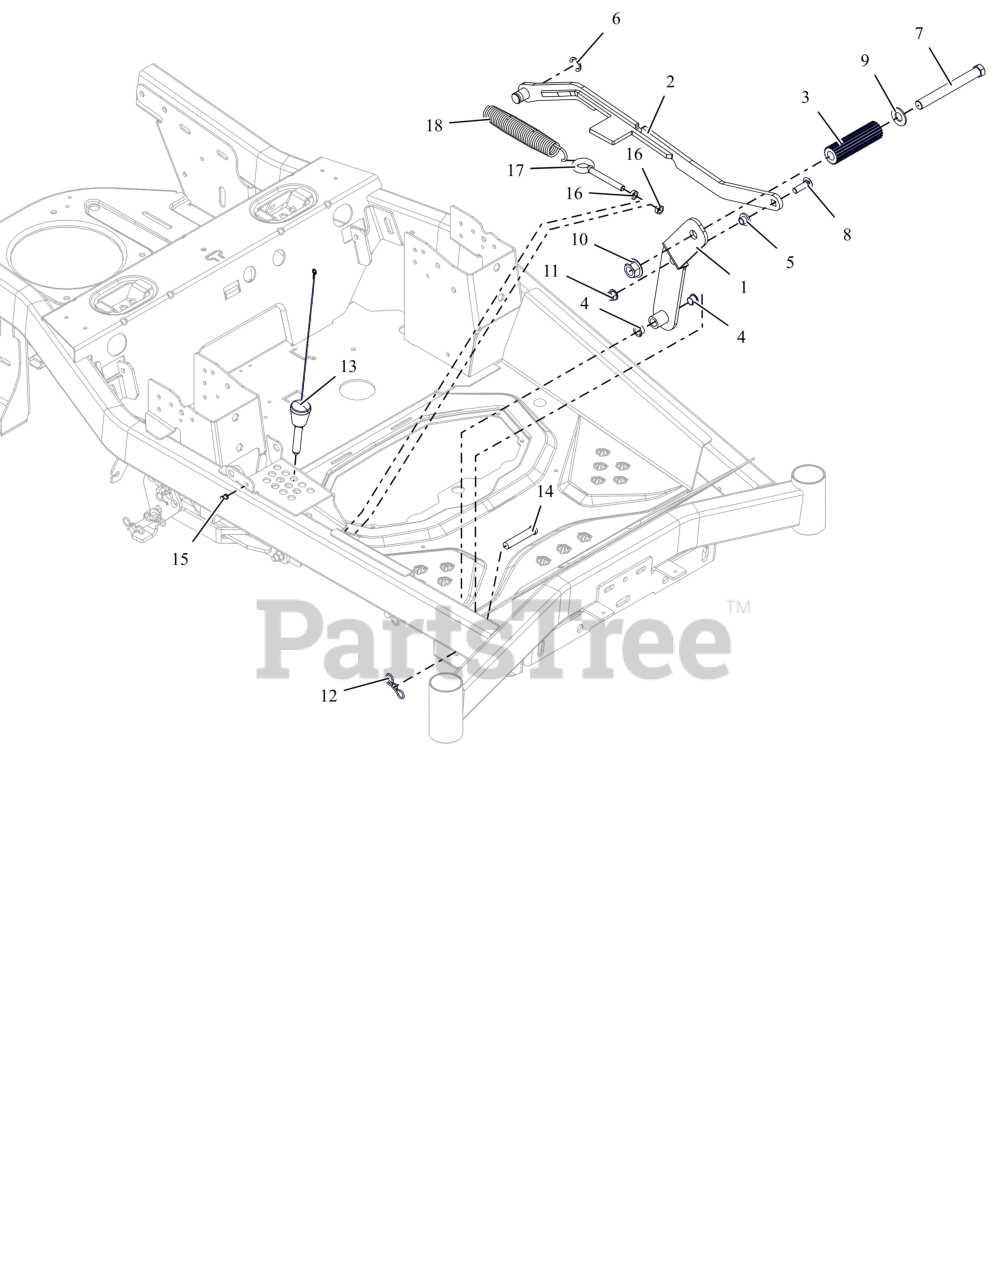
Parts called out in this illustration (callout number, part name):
1	WLDMT- FOOT PEDAL-ORG
2	LINK- DECK LIFT-ORG
3	ROD, FOOT PEDAL (BLACK)
4	BUSHING, POLYLINER-.50 SPLIT
5	BSHG-FLG .385X.500X.875X.406
6	E-RING .750X.050
7	BLT, HEX .62-11X5.50 G5 FBP
8	BLT,RHSSN .38-16X1.25 G5 ZCC
9	WSHRFLT 5/8SAE CARBHARD FBP
10	NUT,FLG-TOP LK .625-11 FBP
11	NUT-LK-CTR-FLG .375-16 GF ZCC
12	PIN, BOWTIE .091X1.875 ZCC
13	PIN- MAGNETIC .50X2.70
14	PIN-CLEV .494X2.50 BRIGHT ZINC
15	POST, & SCREW, PUSH LOCK .25 X .25
16	NUT-JAM .375-16 G2 ZCC
17	BOLT, EYE .38-16X4.50 .75 DIA
18	SPRG, EXTENSION
